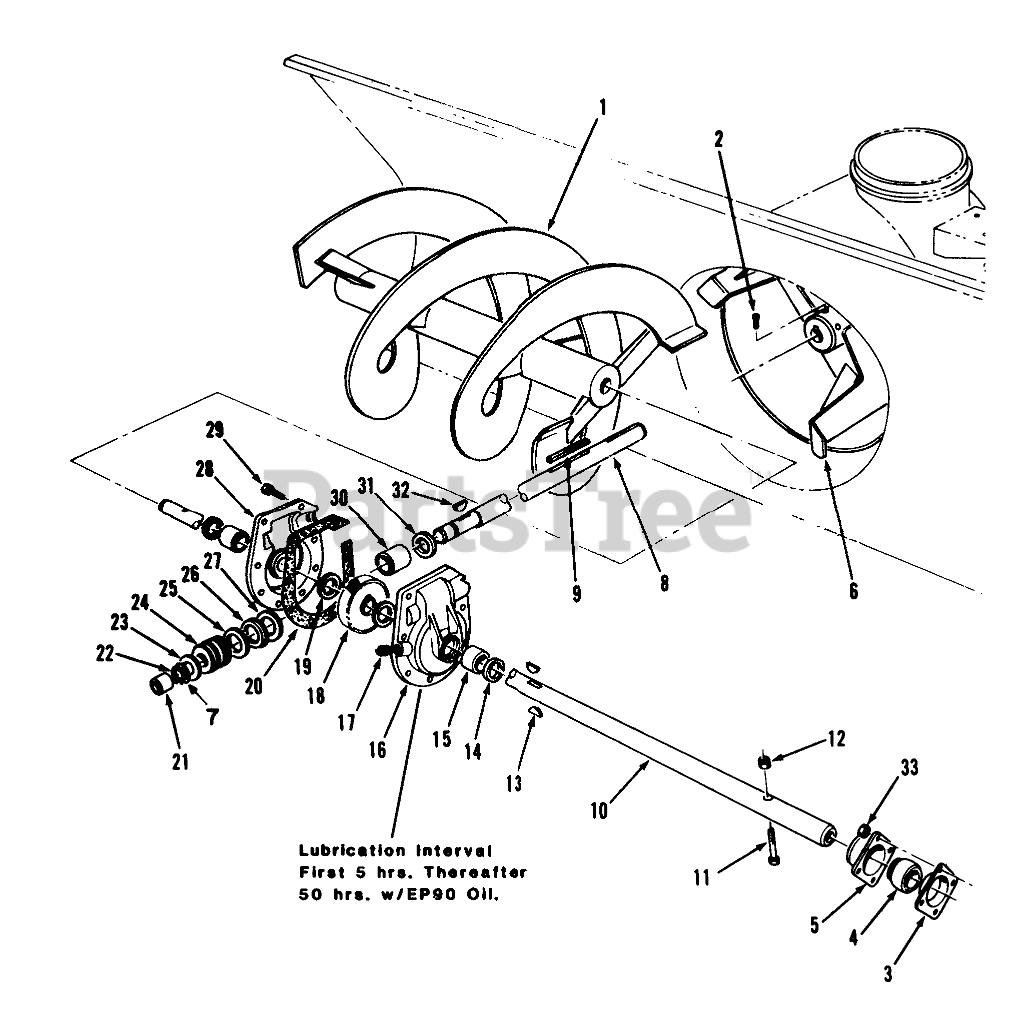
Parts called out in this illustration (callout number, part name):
1	Auger RH
2	Screw-Sq. Hd. Set
3	BEARING-FLANGE, REAR
4	BEARING
5	BEARING-FLANGE, FRONT
6	IMPELLER ASM
7	WASHER-SHIM
8	SHAFT-IMPELLER
9	Washer
10	SHAFT-AUGER
11	Bolt
12	NUT-LOCK, NI
13	KEY-WOODRUFF
14	SEAL-OIL
15	BUSHING
16	LH GEAR CASE ASM
17	PLUG-PIPE, SQH
18	GEAR-WORM, 27T
19	WASHER-THRUST
20	GASKET-CASE, GEAR
21	BUSHING
22	Ring-Snap
23	WASHER-THRUST
25	THRUST-WASHER
26	BEARING-THRUST
27	WASHER-THRUST
28	RH GEAR CASE ASM
29	SCREW-TAPTITE
30	BUSHING-SPECIAL
31	RING-QUAD
32	KEY-WOODRUFF
33	NUT-LOCK, NI
